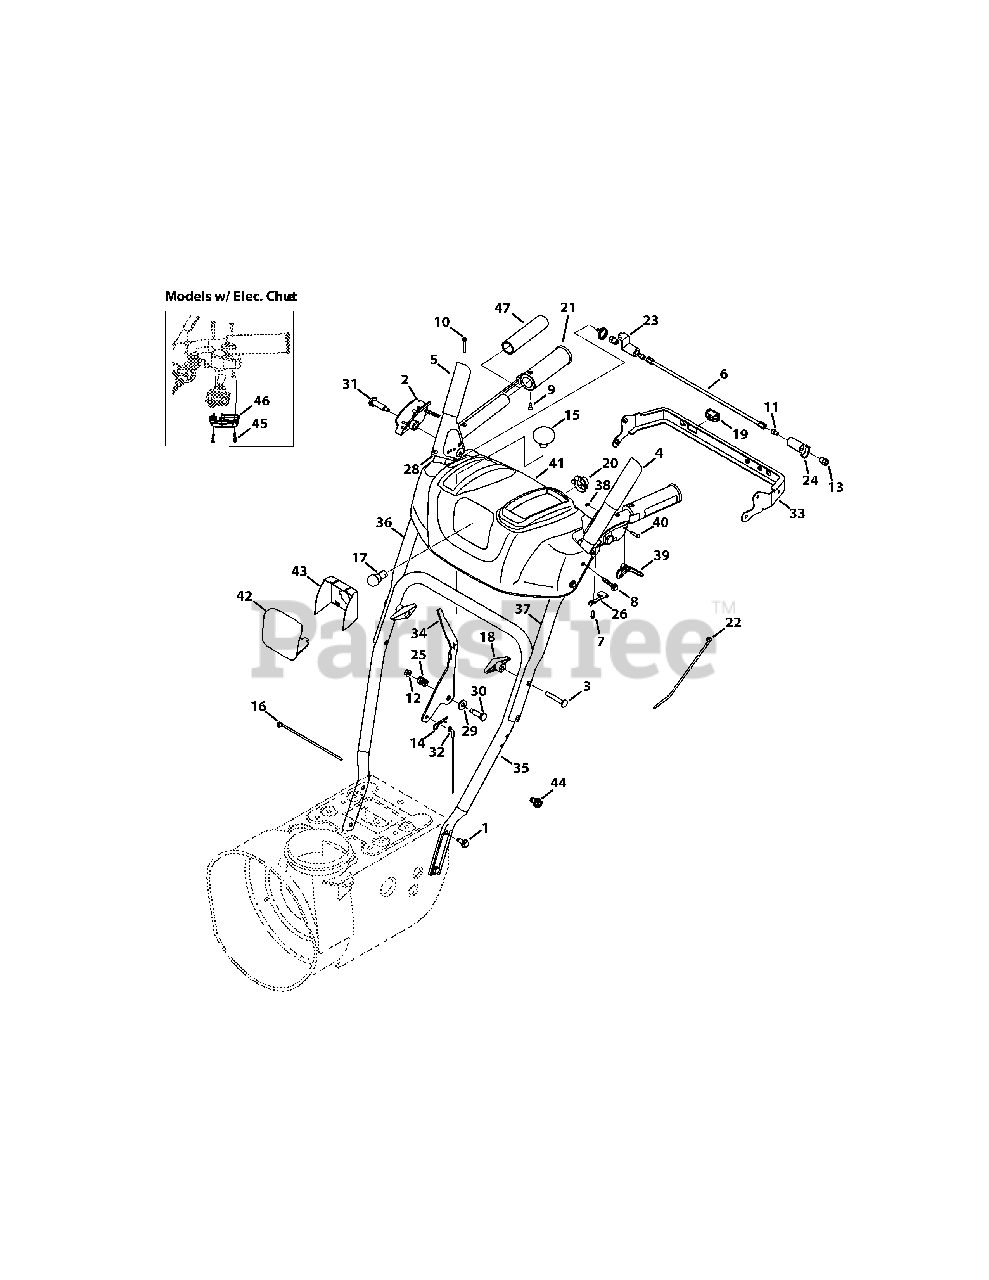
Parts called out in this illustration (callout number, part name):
1	Screw, Taptite, 5/16-18 x .750
2	Clutch Lock, RH
2	Clutch Lock, LH
3	Screw, Carriage, 5/16-18 x 2.50
4	Auger Engage, Red, LH
4	Auger Engage, Black, LH
5	Drive Engage, Red, RH
5	Drive Engage, Black, RH
7	Screw, Plastite, 8-16 x .50
8	Screw, Taptite, 1/4-20 x 1.625
9	Screw, 10-16 x 0.625
10	Screw, 10-24 x 1.375
11	Screw, 1/4-20 x .50
12	Nut, Flangelock, 1/4-20
13	Nut, Hex, 1/4-20
14	Click Pin, .092 x 1.64
15	Shift Knob
16	Cable Tie, 7"
18	Wing Knob, 5/16-18
19	Heated Grip Switch
20	Lamp Socket
21	Heated Grip
22	Cable Tie, Push Mount
23	Plate, Lock
24	Cam, Clutch Lock
25	Compression Spring, .39 x .60 x .88
26	Clutch Lock Spring
27	Torsion Spring, 0.8156 x .3038
28	Rubber Bumper
29	Washer, Flat, .385 x .87
30	Screw, Shield, .374 x 1.05
31	Screw, Shoulder, .437 x 1.345 x 1/4-20
32	Speed Selector Cable
35	Lower Handle
36	Upper RH Handle
37	Upper LH Handle
39	Steering Trigger Control, Red
40	Steering Trigger Pin, 3/16
41	Handle Panel
42	Lens Panel
43	Lens Label
44	Screw, TT, 1/4-20 x .500 (For ground wire)
45	Screw, .159 OD x .610
46	Housing Cover (Elec Chute)
47	Grip, 1.0 ID x 5.0 LG
